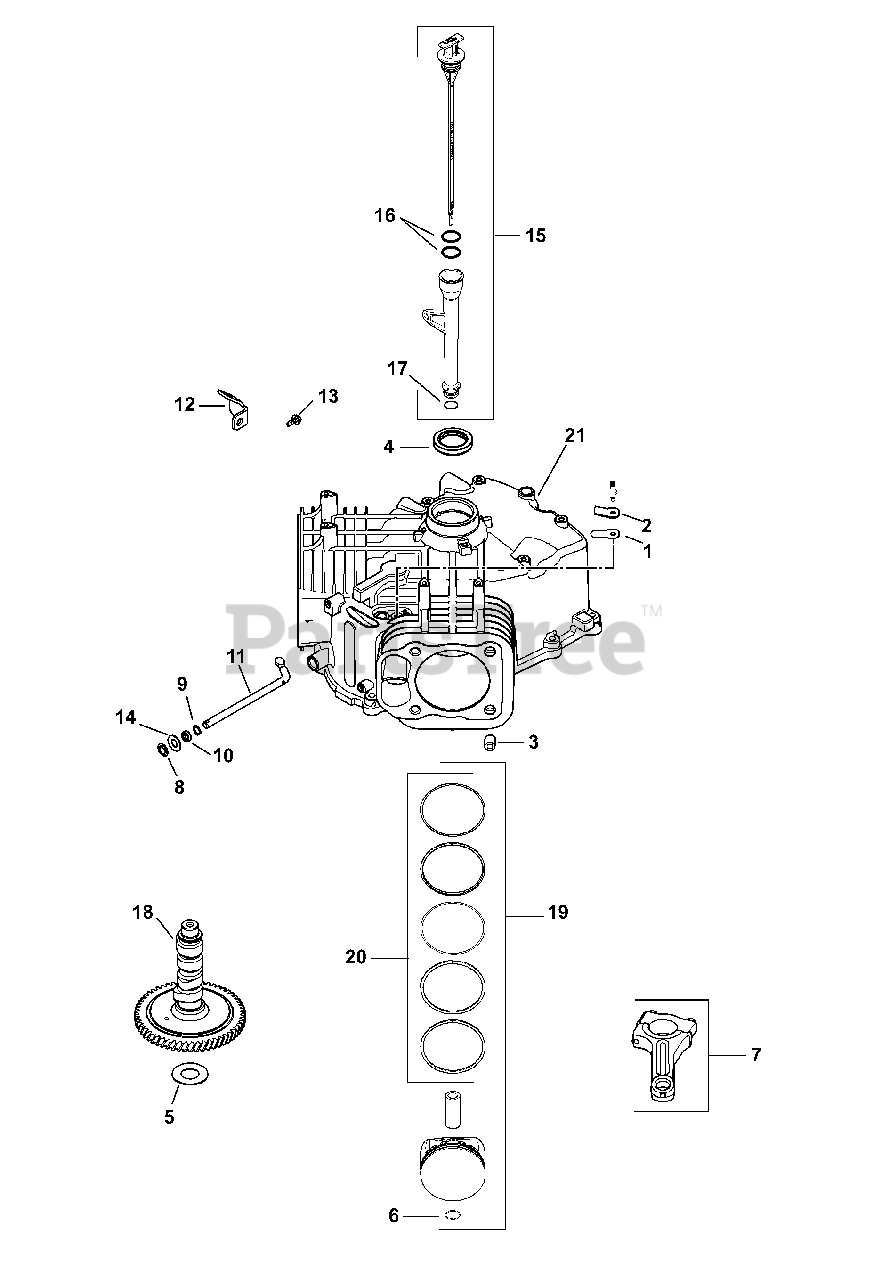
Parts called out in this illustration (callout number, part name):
1	Breather Reed
2	Breather Reed Retainer
4	Oil Seal, 1.78 x 1.26
5	Camshaft Shim (White, .028)
5	Camshaft Shim (Blue, .03)
5	Camshaft Shim (Red, .032)
5	Camshaft Shim (Yellow, .034)
5	Camshaft Shim (Green, .036)
5	Camshaft Shim (Gray, .038)
5	Camshaft Shim (Black, .04)
6	Piston Pin Retainer
7	Connecting Rod (STD)
8	Ring Retainer
9	Flat Washer, 11/32
10	Governor Cross Shaft Seal
11	Governor Cross Shaft
12	Oil Fill Tube Bracket
13	Flange Screw, M5 x .8 x 13
14	Flat Washer, 9mm
17	Lower Oil Fill Tube O-Ring
18	Camshaft Assembly
19	Kit,Piston W/Rng Set (Std) 83Mm
19	Kit,Piston W/Ring (0.08) 83Mm
19	Kit,Piston W/Ring (0.25) 83Mm
20	Ring Set (Std)
20	Ring Set (.08)
20	Ring Set (.25)
21	Crankcase
